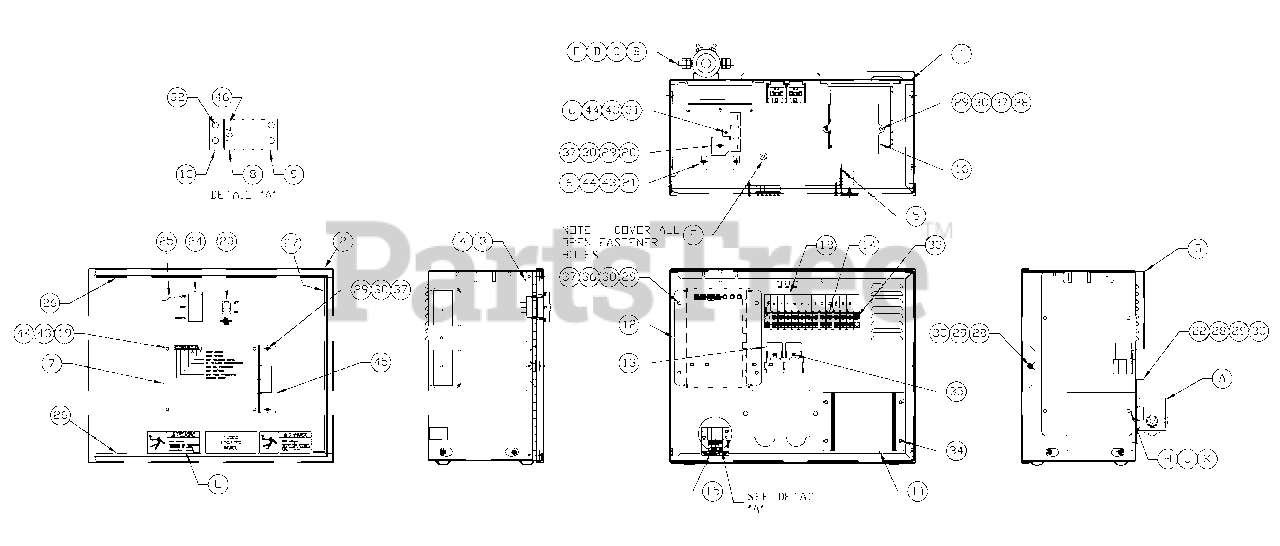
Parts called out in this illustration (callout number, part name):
1	ENCL HSB CONTROL PANEL
2	COVER CONTROL PANEL
3	HINGE CONTINUOUS H-PANEL
4	RIVET POP .125 X .275 SS
5	SCREW PPPH HI-LO #4-24 X 3/8
6	WASHER FLAT M3
7	ASSY PCB R-200 1800 RPM 2.4L
8	HOLDER FUSE WICKMANN 178.6150
9	ADPTR RH SIDE WICKMAN 178.6191
10	ADPTR LH SIDE WICKMAN 178.6192
11	ASSY PCB 2AMP 12V UL BATT CHGR
12	ASSY VOLTAGE REGULATOR 60HZ
13	RELAY 12VDC C FORM W/DIODE
14	BLOCK TERM 20A 12 X 6 X 1100V
15	DECAL CPL CONTROL PANEL FUSES
16	ASSY PCB BOSCH GOV DRIVER
18	DECAL CPL 3.9L TB1
19	SPACER 9.5H 3.2 ID
20	DIO BRIDGE 25A 600V
21	CIRCT BRK 7 X 1 ETA 46-500-P
22	PLATE HARNESS CLAMP
23	SWITCH RKR DPST 125V SPD
24	SWITCH RKR DPDT ON-OFF-ON
25	DECAL, CONTROL HSB
26	SEAL COVER 3.18 X 12.7 X 382
27	SEAL COVER 3.18 X 12.7 X 283
28	SCREW HHPM M5-0.8 X 12
29	WASHER FLAT M5
30	WASHER LOCK M5
31	RES WW 15R 5% 25W QK CONN
32	SCREW PHTT M3.5-0.6 X 10
33	SCREW PHTT M3.5-0.6 X 16
34	SCREW PHTT M4-0.7 X 12 ZYC
35	SCREW PHTT M4-0.7 X 10 ZYC
36	SCREW PPHM M5-0.8 X 12 ZNC
37	NUT HEX M5-0.8 G8 CLEAR ZINC
38	SCREW PPHM M5-0.8 X 30 SS
43	WASHER LOCK M3
44	NUT HEX M3-0.5 G8 YEL CHR
45	SUPPORT ANGLE PCB
46	FUSE ATO TYPE 15 AMP (BLUE)
A	RELAY SOLENOID 12VDC PNL MNT
B	SCREW HHC 1/4-20 X 3/4 G5
C	WASHER FLAT 1/4-M6 ZINC
D	WASHER LOCK M6-1/4
E	NUT HEX 1/4-20 STEEL
F	SEAL WEATHER .45"DIA
G	COVER CONTROL PANEL SIDE
H	SCREW PPHM M5-0.8 X 12 ZNC
J	WASHER LOCK M5
K	WASHER FLAT M5
